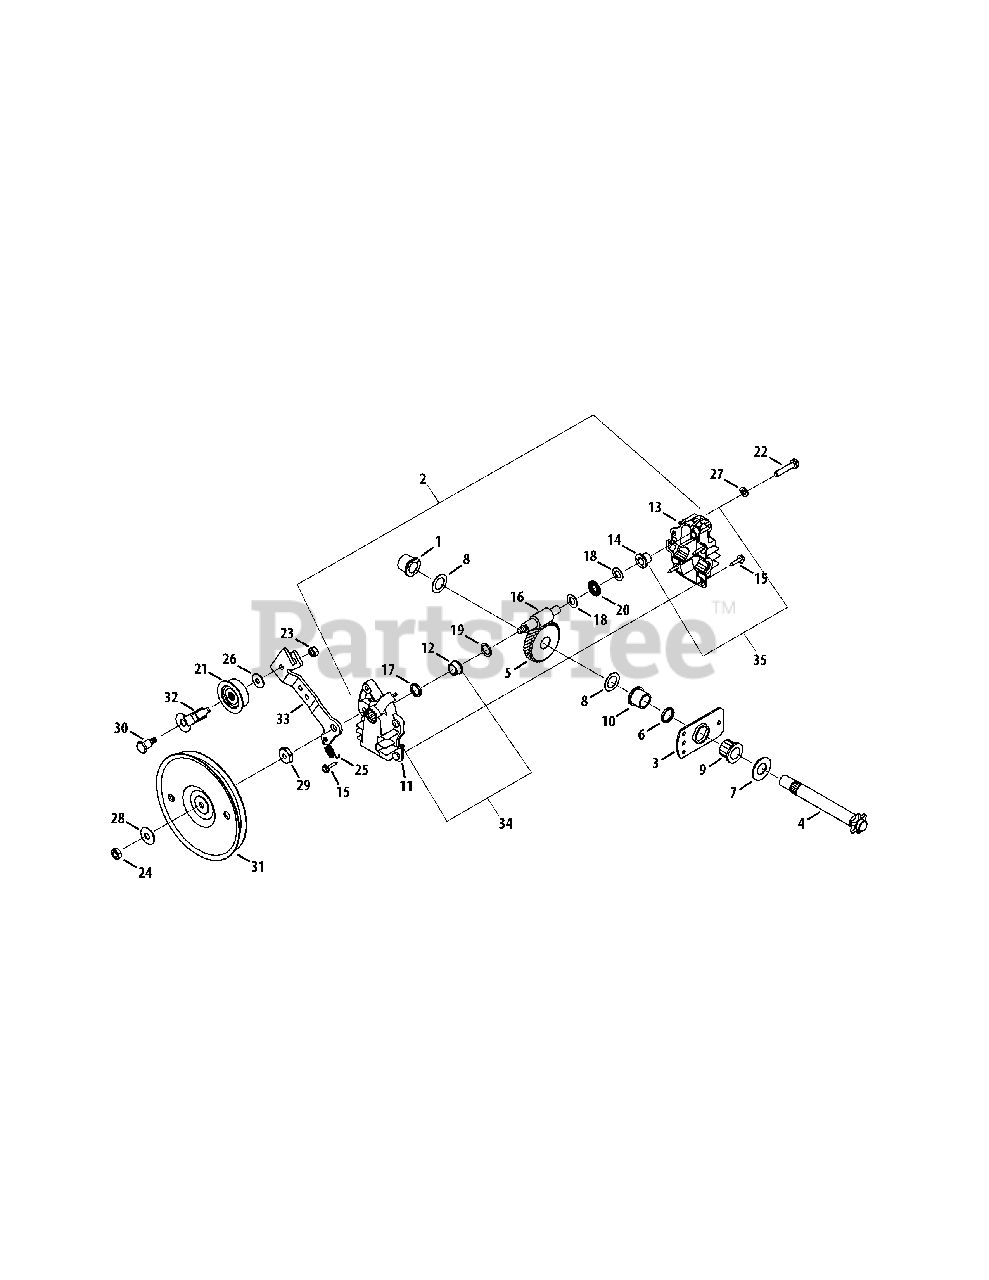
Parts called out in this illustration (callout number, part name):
1	Flange Bearing.566 ID
2	Shredder Transmission Assembly
3	Hex Bearing Cup
4	Output Shaft 6T Sprocket
5	Helical 34T Gear
7	Flat Washer, .64 ID x 1.24 OD
8	Flat Washer, 5/8 x 1.0
9	Hex Flange Bearing, .631 ID
10	Flange Bearing, .629 ID
11	Lower Housing
12	Flange Bearing, .503 ID
13	Upper Housing
14	Flange Bearing, .378 ID
15	Hex Washer Screw, #10-16 x.75
16	Pinion Shaft 10T
18	Thrust Washer, .382 ID x.684 OD
19	Flat Washer, .504 ID x.70 OD
20	Thrust Bearing, .375 ID x.812 OD
21	Idler Pulley Assembly W/ Bearing
22	Hex Cap Screw, 1/4-20 x 1.25
23	Hex Nut, 1/4-28
24	Hex Jam Nut, 5/16-24 LH Thd
25	Extension Spring, 1.12 Lg
26	Bell Washer, .265 ID x.75 OD
27	Lock Washer, 1/4
28	Bell Washer, .325 ID x.930 OD
29	Shoulder Spacer, .375 ID x.165 OD
30	Shoulder Bolt, 1/4-28 x.375
31	Flat Pulley 5.06 Dia
32	Belt Keeper
33	Idler Bracket
34	Lower Housing Assembly
35	Upper Housing Assembly
